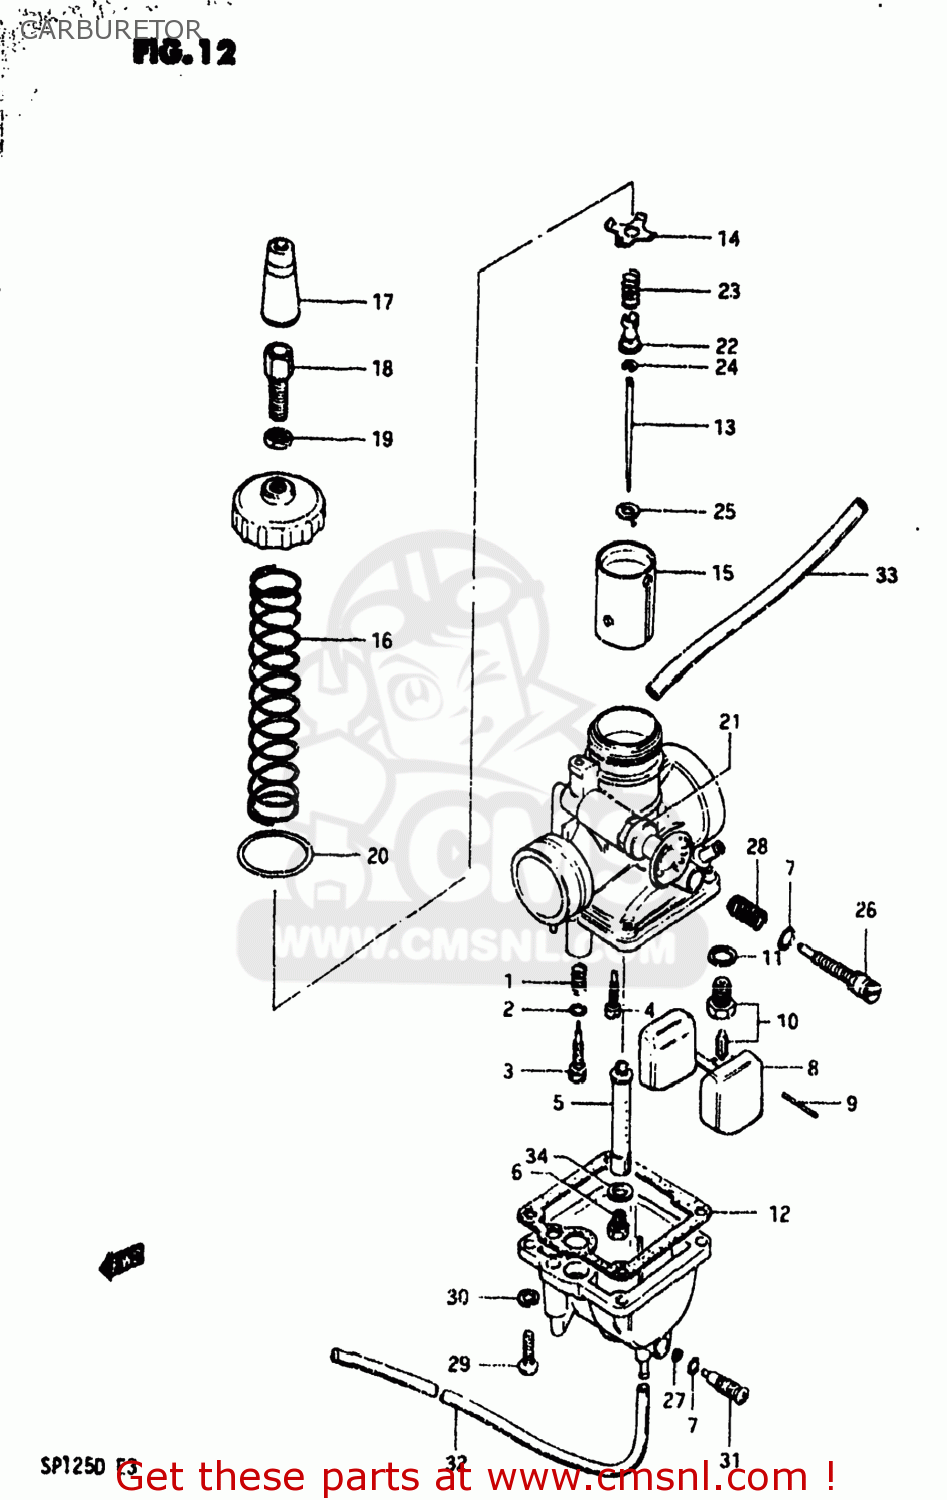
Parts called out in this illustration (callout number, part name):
0	CARBURETOR ASSEMBLY
1	SPRING,THROTTLE ADJUST
2	O-RING
3	SCREW,PILOT AIR
4	JET,PILOT
5	JET,NEEDLE
6	JET,MAIN
7	O-RING
8	FLOAT
9	PIN,FLOAT
10	VALVE ASSY,NEEDLE(ID:2.0)
11	GASKET,NEEDLE VALVE SE
12	GASKET,FLOAT CHAMBER (NAS)
13	NEEDLE JET
14	PLATE,THROTTLE VALVE
15	VALVE,THROTTLE
16	SPRING,THROTTLE VALVE
17	CAP
18	ADJUSTER,CABLE
19	NUT,CABLE ADJUSTER LOCK
20	O-RING,MIXING CHAMBER
21	VALVE ASSEMBLY,STARTER
22	HOLDER,NEEDLE
23	SPRING,NEEDLE JET
24	E-RING
25	RECEIVER,NEEDLE
26	SCREW,THROTTLE STOP
27	O-RING,DRAIN PLUG
28	SPRING,THROTTLE SCREW
29	SCREW
30	LOCK WASHER
31	PLUG,DRAIN
32	HOSE
33	HOSE
34	WASHER,MAIN JET
